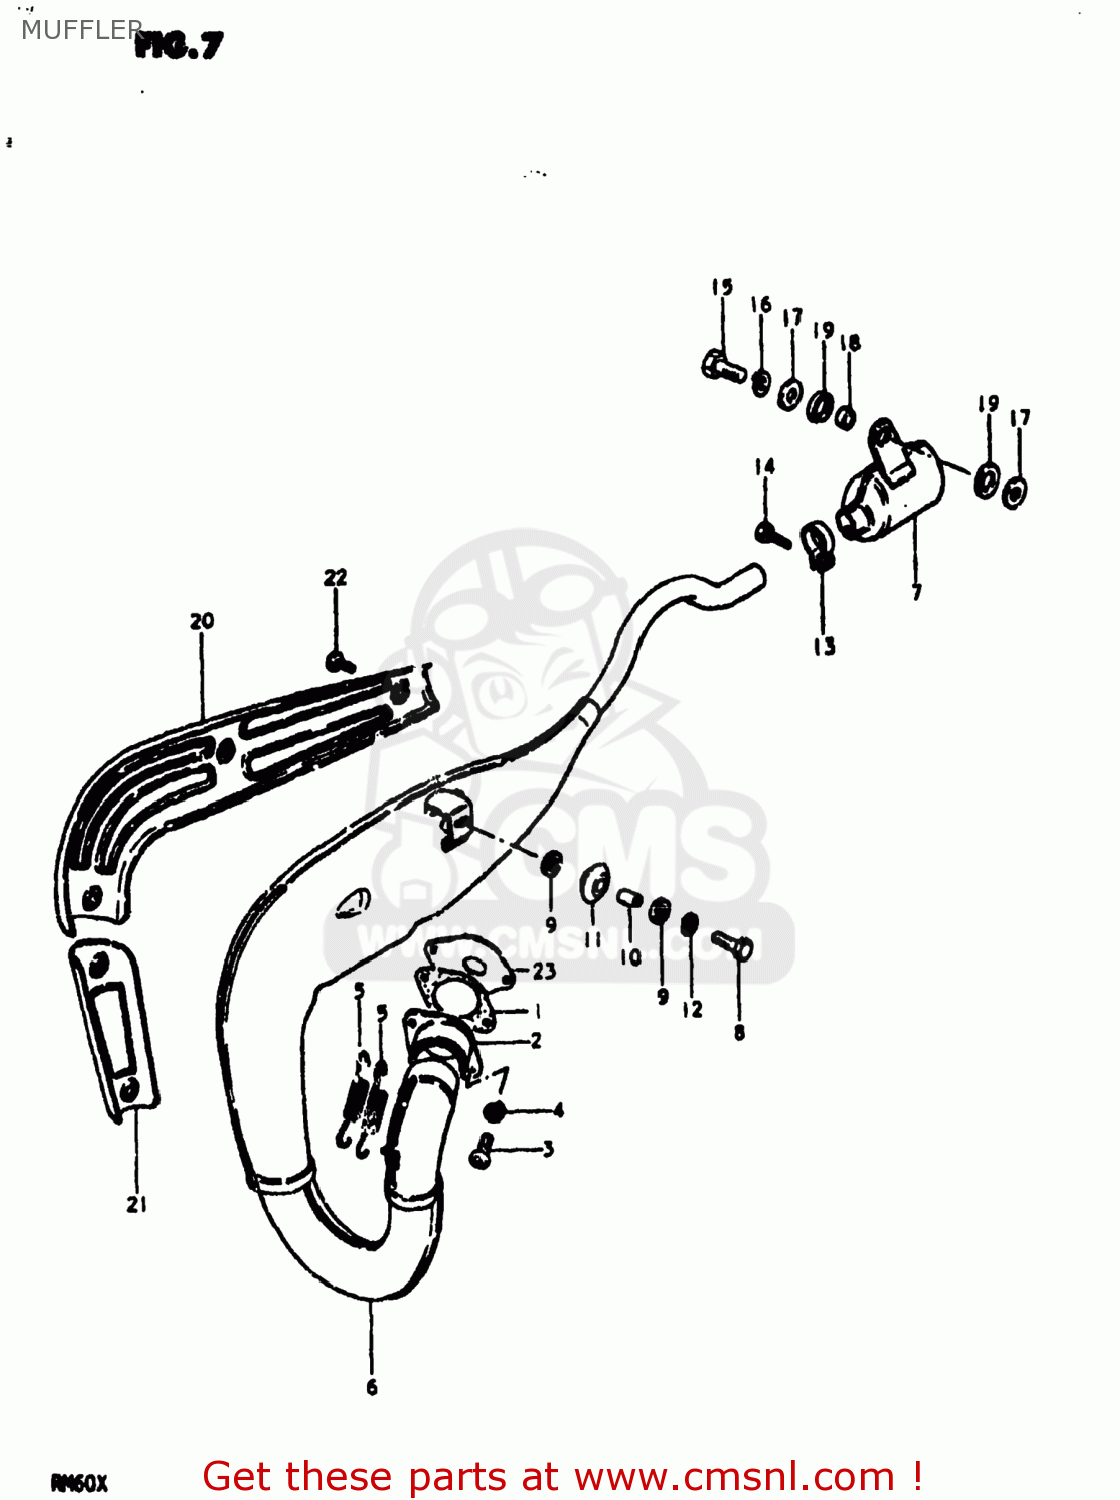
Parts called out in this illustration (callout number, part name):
1	GASKET,EXHAUST PIPE (MCA)
2	PIPE,CENTER EXHAUST
3	SCREW
4	LOCK WASHER
5	SPRING
6	BODY,MUFFLER
7	BODY,MUFFLER
8	BOLT (8X30)
9	WASHER (8.7X22X2)
10	SPACER (8X12X15)
11	DAMPER,MUFFLER,FR
12	LOCK WASHER
13	CLAMP
14	BOLT(6X20)
15	BOLT
16	LOCK WASHER
17	WASHER
18	SPACER (8.6X13.8X9)
19	CUSHION
20	COVER,MUFFLER NO.1
21	COVER,MUFFLER
22	SCREW
23	PLATE,EXHAUST PIPE
